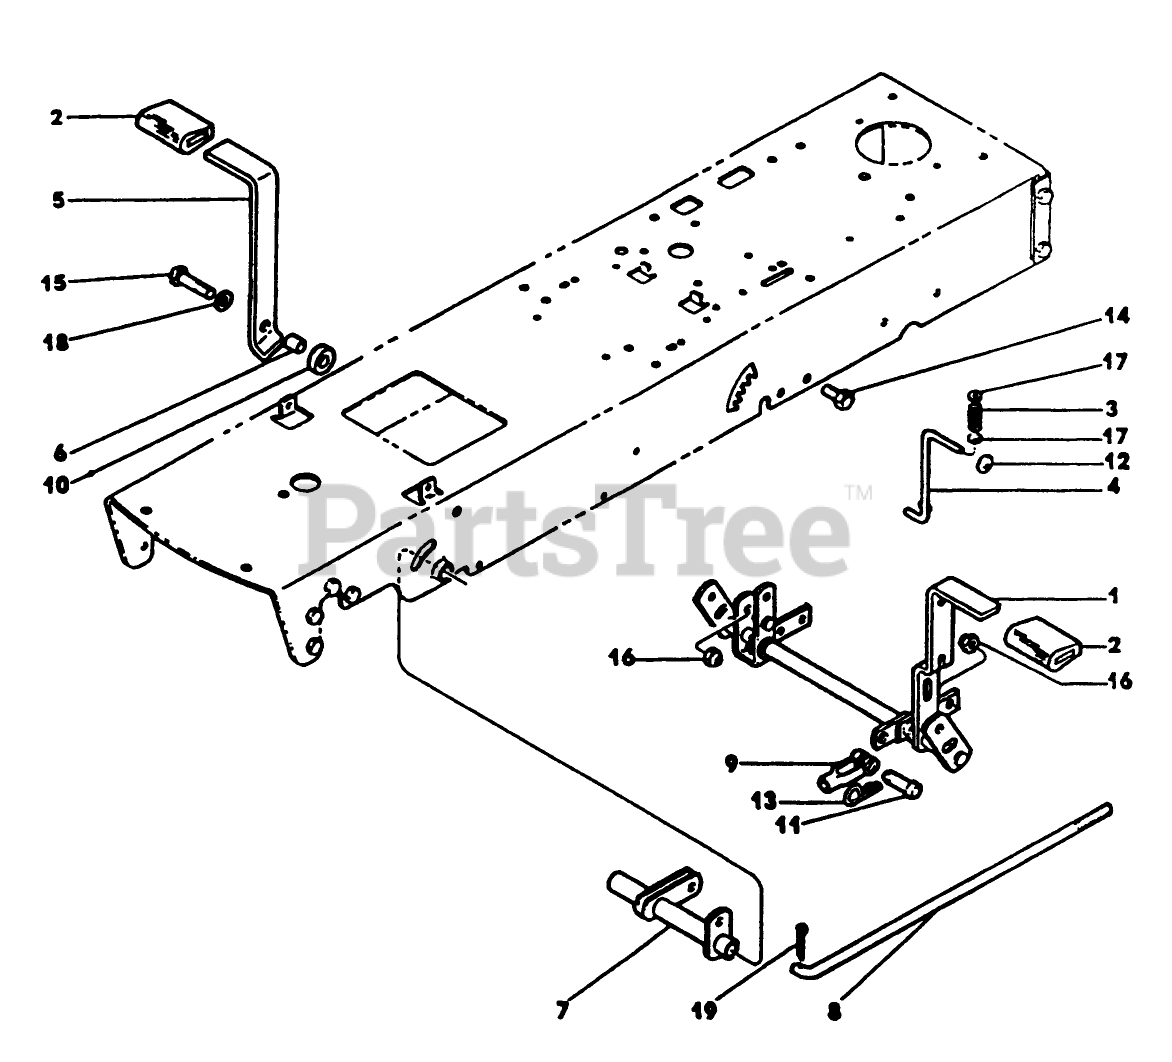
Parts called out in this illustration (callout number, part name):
2	GRIP
7	CROSS SHAFT WA*B
11	PIN CLEVIS
13	PIN - SPRING CLIP
16	NUT-LOCKING
18	WASHER
